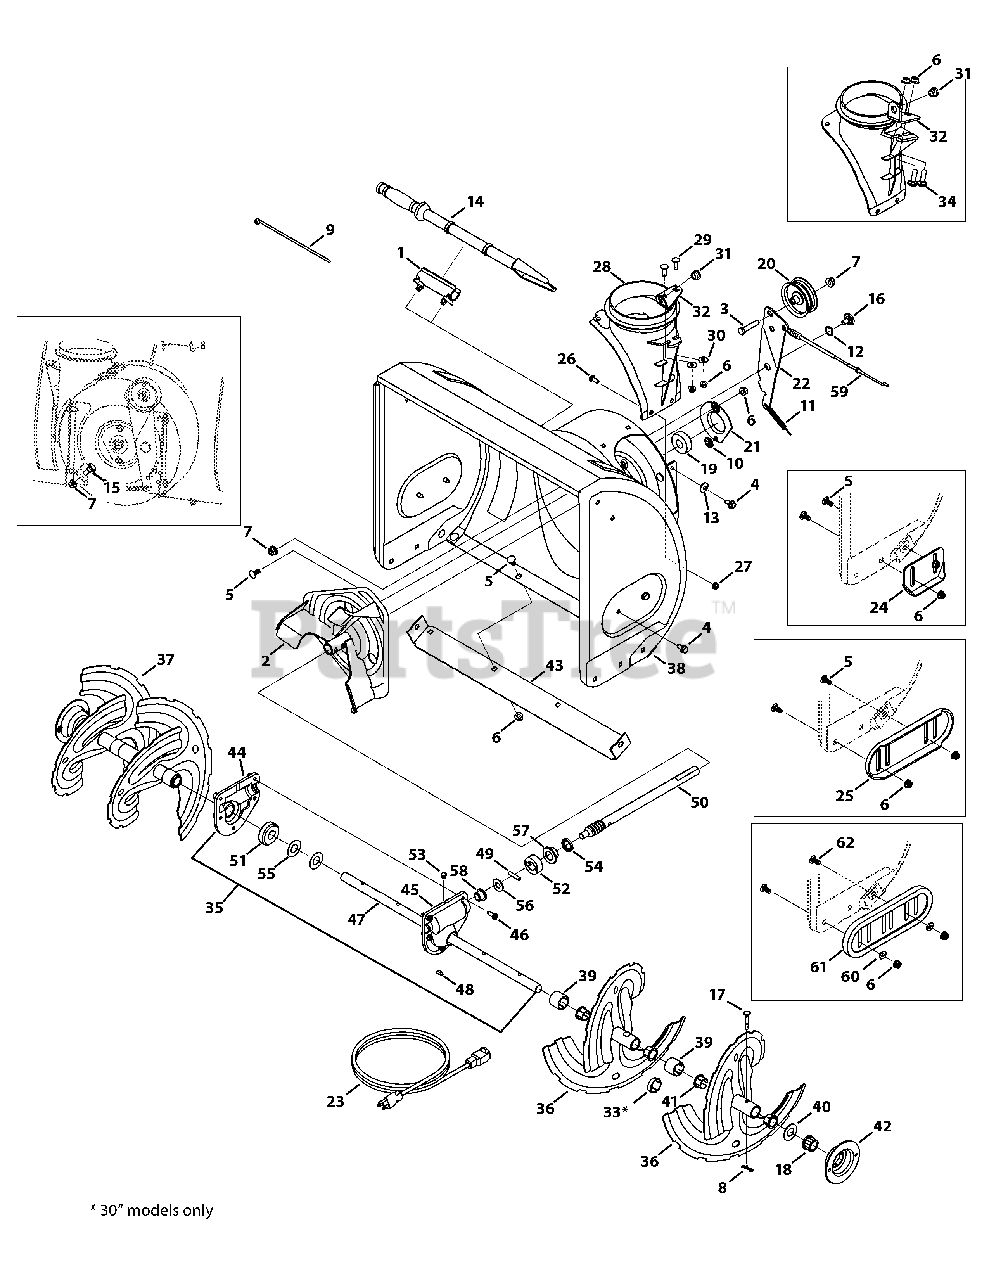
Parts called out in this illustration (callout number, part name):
1	Cleanout Tool Mount
2	Impeller Assembly, 12"
3	Hex Screw, 3/8-16 x 1.75
4	Hex Washer Screw, 5/16-18 x .750
5	Carriage Bolt, 5/16-18 x .750
6	Flange Lock Nut, 5/16-18
7	Flange Lock Nut, 3/8-16
8	Bow-Tie Cotter Pin
9	Cable Tie, 3/16 x .05 x 7.4
10	Push Nut, .25 Dia.
11	Extension Spring
12	Wave Washer, .625 x .885 x .015
13	Bell Washer, .340 x .872 x .060
14	Chute Cleanout Tool
15	Shoulder Bolt, .496 x .336 x 3/8-16
16	Shoulder Screw, .625 x .17 x 3/8-16
17	Shear Pin, .25 x 1.50
18	Hex Flange Bearing, .75 ID
19	Ball Bearing, .75 ID x 1.85 OD
20	Idler Pulley, 2.75 OD
21	Bearing Housing, 1.85 ID
22	Auger Idler Bracket
23	Extension Cord (Electric Start Only)
24	Skid Shoe, Standard Steel
24	Skid Shoe Kit, Standard Polymer
25	Deluxe Skid Shoe
26	Carriage Screw, 1/4-20 x .75
27	Flange Lock Nut, 1/4-20
28	Chute Adapter, 5"
28	Chute Adapter, 5" (4-way)
28	Chute Adapter, 5" (side crank)
29	Carriage Screw, 5/16-18 x 1.00
30	Flat Washer, .349 x .879 x .063
31	Plastic Bushing, .380 ID
32	Chute Crank Bracket
33	Spacer, 1.250 x .75 ID x 3/16 LG
34	Carriage Bolt, 5/16-18 x 1.00
35	Gearbox Assembly, 22"
35	Gearbox Assembly, 24"
35	Gearbox Assembly, 26"
35	Gearbox Assembly, 28"
35	Gearbox Assembly, 30"
36	Spiral Assembly, LH
37	Spiral Assembly, RH
38	Auger Housing Assembly, 24" (T-B)
38	Auger Housing Assembly, 26" (T-B)
38	Auger Housing Assembly, 28" (T-B)
39	Spacer, 1.2500 x .75 ID x 1.00
40	Flat Washer, .76 x 1.49 x .06
41	Flange Bushing, .800 ID x .910 OD
42	Bearing Housing, 1"
43	Shave Plate, 24"
43	Shave Plate, 26"
43	Shave Plate, 28"
44	Housing Assembly, RH
45	Housing Assembly, LH
46	Hex Washer Screw, 1/4-20 x .750
47	Auger Axle, 24"
47	Auger Axle, 26"
47	Auger Axle, 28"
48	Hi-Pro Key
49	Dowel Pin, .25 OD x 1.25 LG
50	Worm Shaft, .75 OD
51	Worm Gear 20 T, 22", 24" & 26"
51	Worm Gear 20 T, 28"& 30"
52	Thrust Collar, .756 ID x .600
53	Plug, 1/4 x .437
54	Oil Seal, .75 x 1.131 x .188
55	Flat Washer, .760 ID x 1.50 ID
56	Flat Washer, .51 x 1.12 x .06
57	Flange Bearing, .75 ID x 1.0 OD x .59
58	Flange Bearing, .50 ID x .75 OD x .59
59	Auger Drive Cable
60	Washer, Flat, .349 x .879
61	Polymer Slide Shoe Deluxe
61	Polymer Reversible Shoe Kit
62	Carriage Screw, 5/16-18 x 1.00
